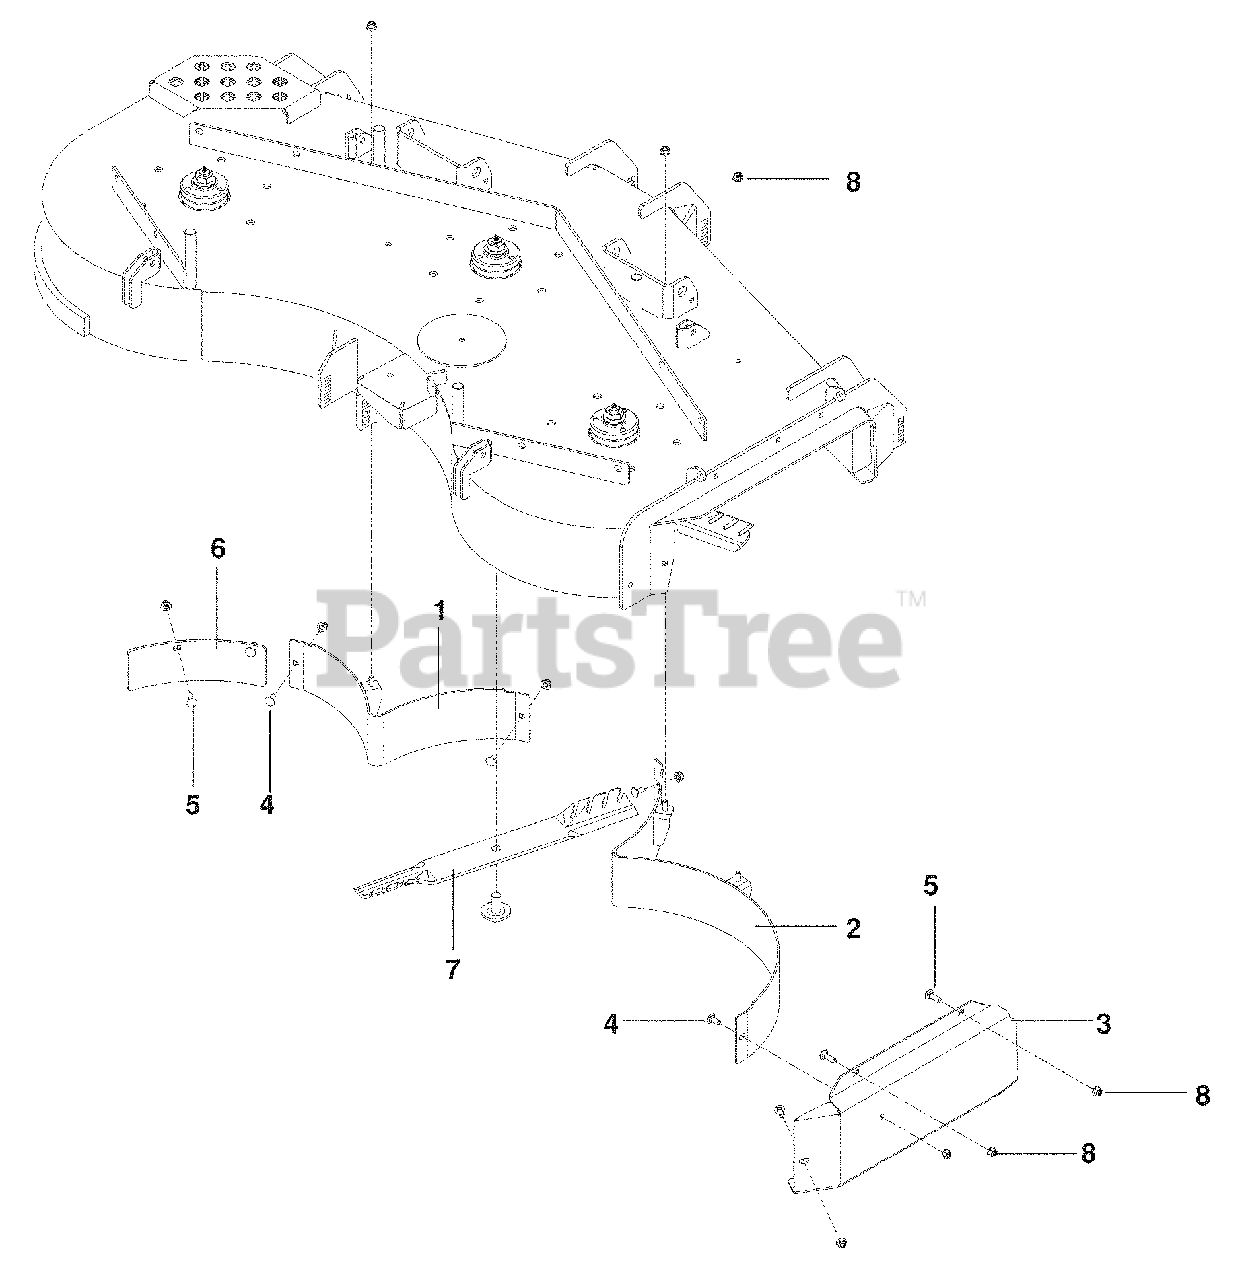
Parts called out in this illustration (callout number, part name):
1	BAFFLE, MULCH LH
2	BAFFLE, MULCH RH
3	CAP, MULCH
4	RHSNB 5/16-18 x ¾ GR 5
5	RHSNB 5/16-18 X 1 GR 5
6	BAFFLE, LH CORNER
7	BLADE, 21" GATOR
8	NUT 5/16-18 HEX FLNG NYLOC
